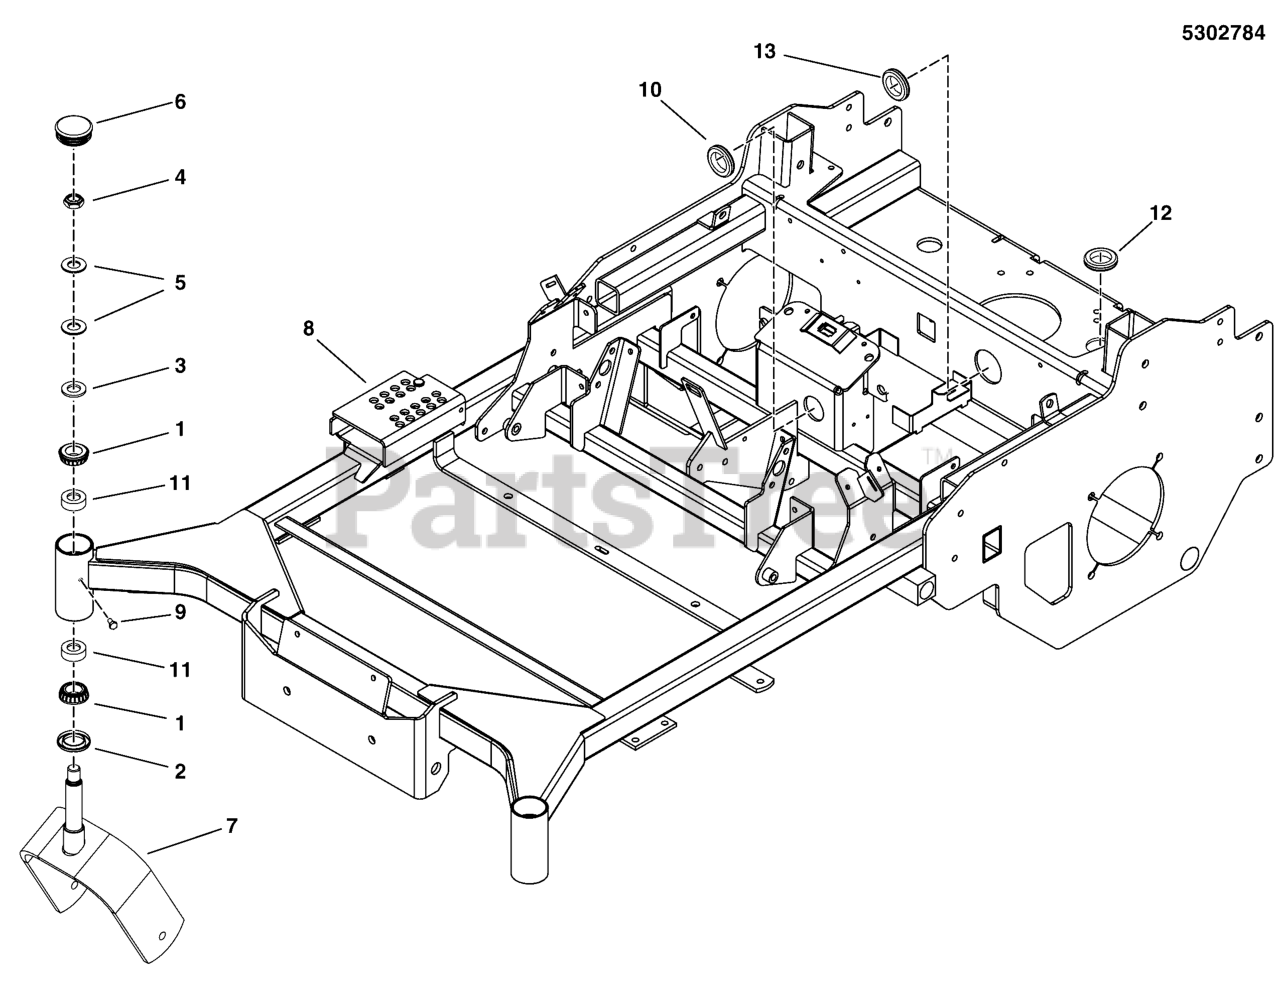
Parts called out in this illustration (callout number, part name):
1	BEARING, TAPERED ROLLER
2	SEAL, GREASE
3	WASHER, 3/4 SAE
4	NUT, 3/4-16, HEX JAM NYLON LOCK
5	WASHER, BELLEVILLE - 1.500 X .755
6	CAP, GREASE, LOW PROFILE
7	WELD, CASTER YOKE - RED
8	WELD, FRAME, 200XT-61" - RED
8	WELD, MAIN FRAME, 200XT-61" - RED
8	WELD, MAIN FRAME, S200XT
9	BOLT, 1/4-28 X 1/2, GD5 YZ
10	GROMMET, 7/8"ID, 1/4" THICK STK
11	CUP, BEARING (SV)
12	GROMMET, 7/8
13	GROMMET, 2" ID
